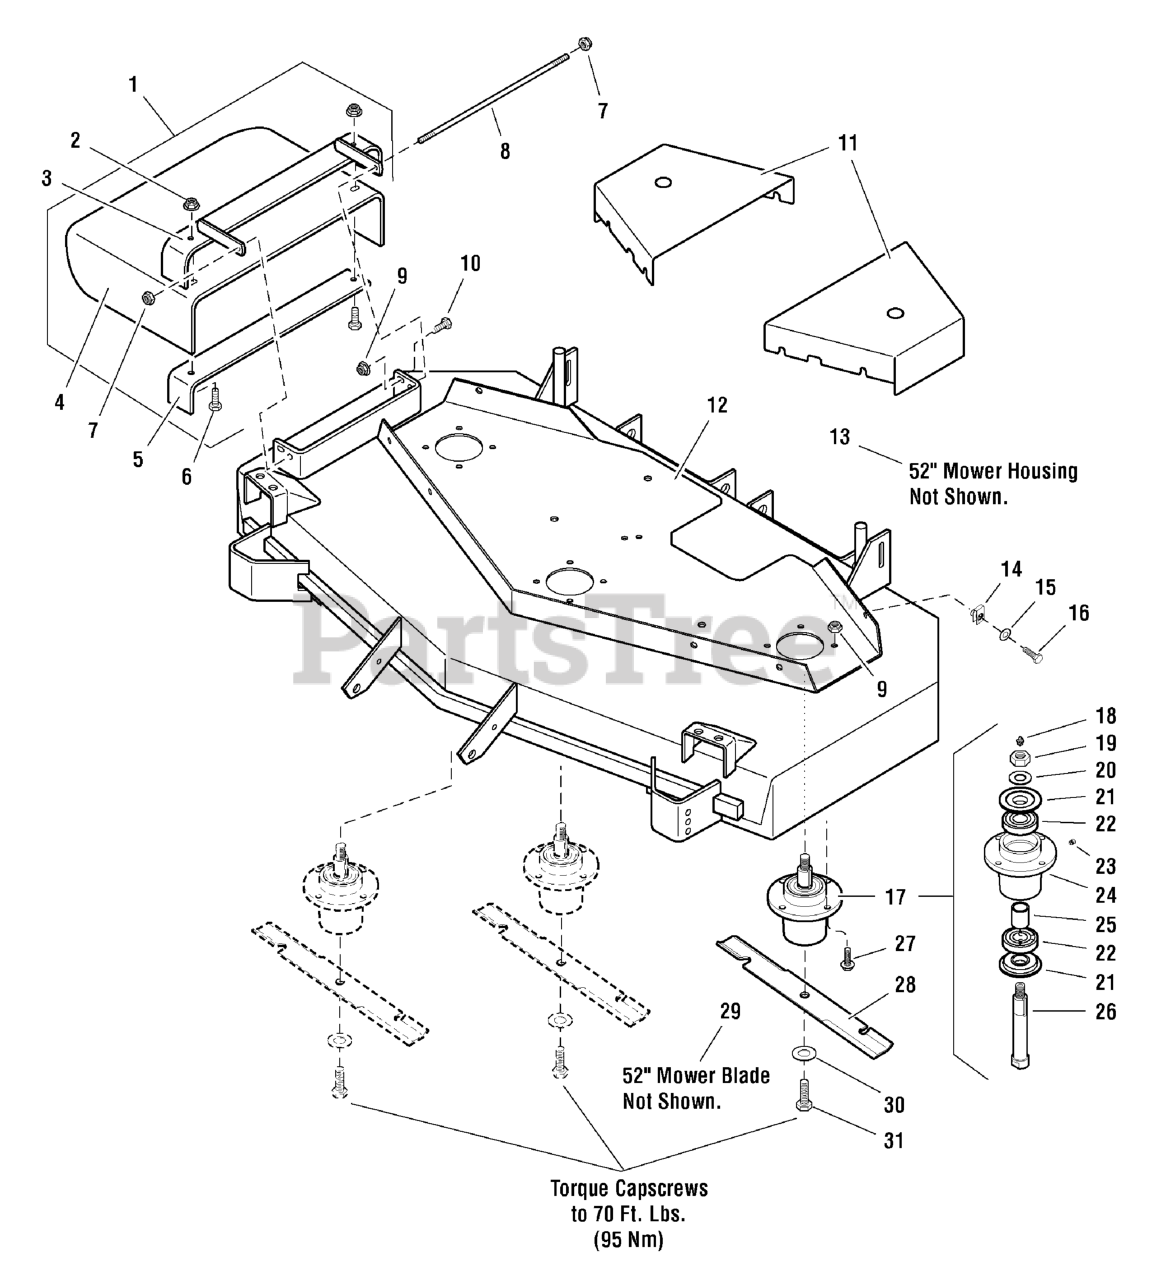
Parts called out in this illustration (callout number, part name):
1	RUBBER CHUTE ASSEMBLY, Complete
2	NUT, 3/8-16 Hex Nylock Flange
3	CHUTE FRAME
4	CHUTE, DISCHARGE RUBBER, 44/48/52
5	CHUTE SUPPORT
6	BOLT, 3/8-16 X 1-1/4" GD5 CZ
7	NUT, 5/16-24 HEX NYLON LOCK
8	ROD, Linkage
9	NUT, 5/16-18 Hex Nylock Flange
10	BOLT, 5/16-18 X 3/4 GD5
11	MOWER HOUSING GUARD
12	DECK SHELL W/DECALS, 48"
14	BODY CLIP, 5/16-18-7GA MATERIAL
15	WASHER, 5/16" SAE
16	BOLT, 5/16-18 X 3/4 GD5
17	ASSM, SPINDLE, LOW PROFILE
18	GREASE FITTING
19	NUT, 3/4-16 Hex
20	WASHER, 3/4 BELLEVILLE
21	TRASH SHIELD
22	BEARING
23	RELIEF VALVE
24	SPINDLE HOUSING
25	SPACER, 1.00 x 1.25 x 1.75
26	SPINDLE SHAFT
27	BOLT, Flange Head, 5/16-18 x 1-1/4
28	MOWER BLADE, 16-1/4"
29	MOWER BLADE, 18"
30	WASHER, 5/8" USS
31	BOLT, 5/8-11 X 1-3/4 GD8
